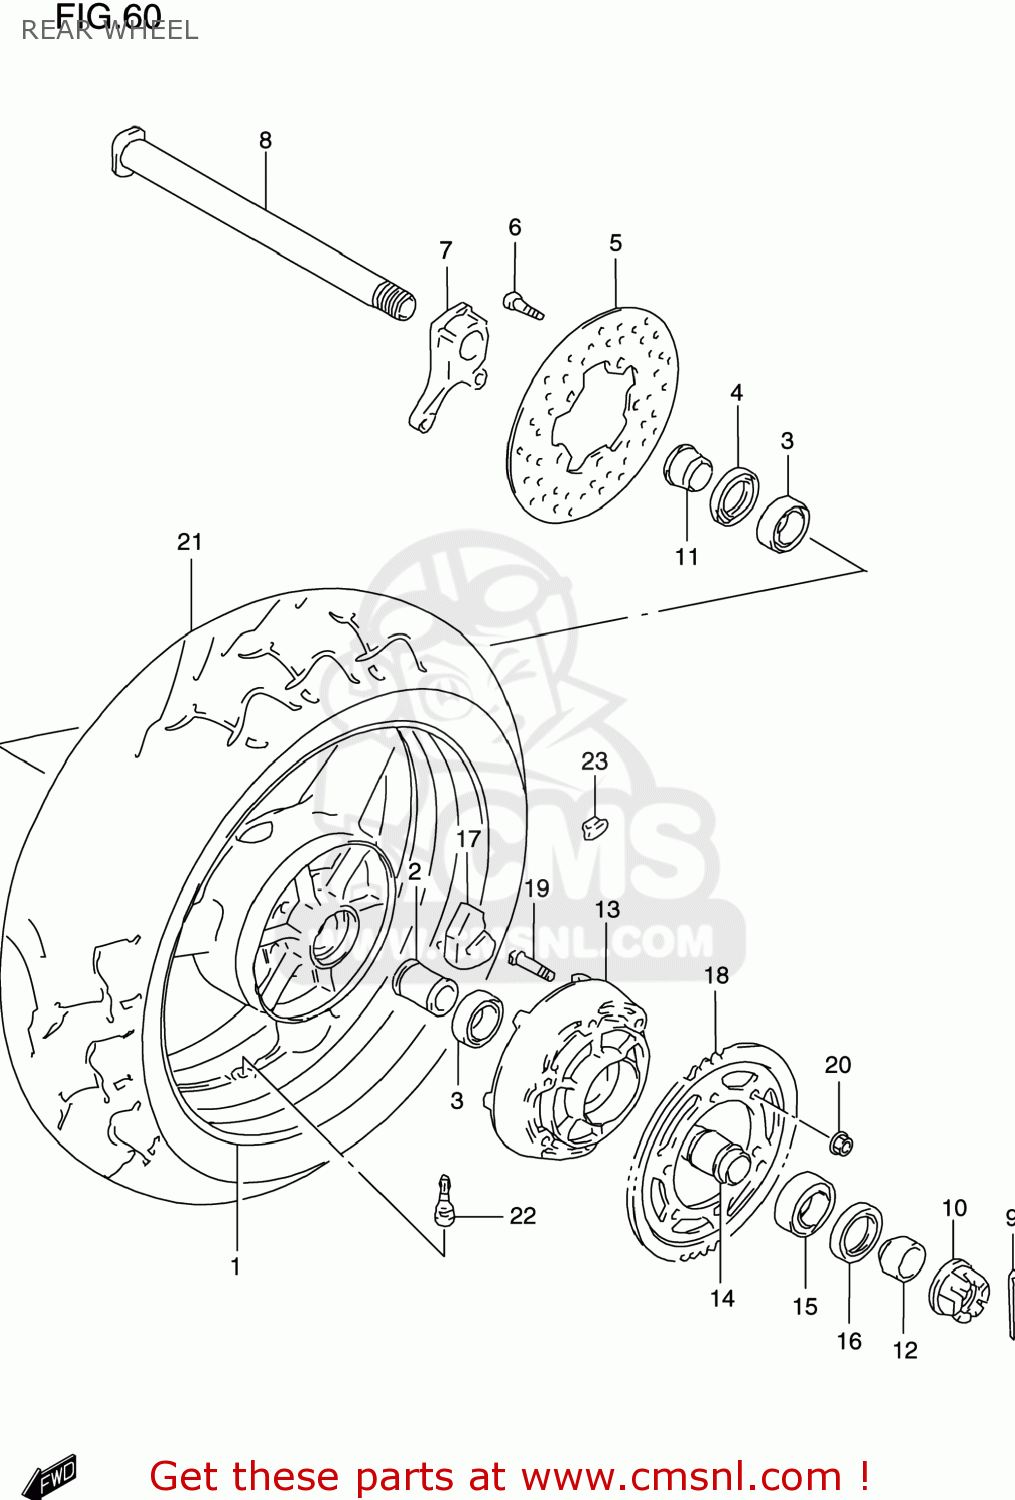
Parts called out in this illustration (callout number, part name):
1	WHEEL,RR(17XMT5.50)
2	SPACER,RR HUB BEARING
3	BEARING(32X58X13)
4	SEAL,OIL(38X58X7)
5	DISC,RR BRAKE
6	BOLT 8X33
7	BRACKET,RR CALIPER
8	AXLE,RR
9	PIN, COTTER
10	NUT
11	SPACER,RR AXLE,R
12	SPACER,RR AXLE,L
13	DRUM,RR SPROCKET
14	RETAINER,RR SPROCKET DRUM
15	BEARING
16	SEAL,OIL(39X65X7)
17	ABSORBER,RR HUB SHOCK
18	SPROCKET,RR(NT:45-525)
19	BOLT
20	NUT
21	TIRE,REAR 180/55 ZR17 (
22	VALVE ASSY,WHEEL RIM(TR412)
23	BALANCER,WHEEL (10G)
